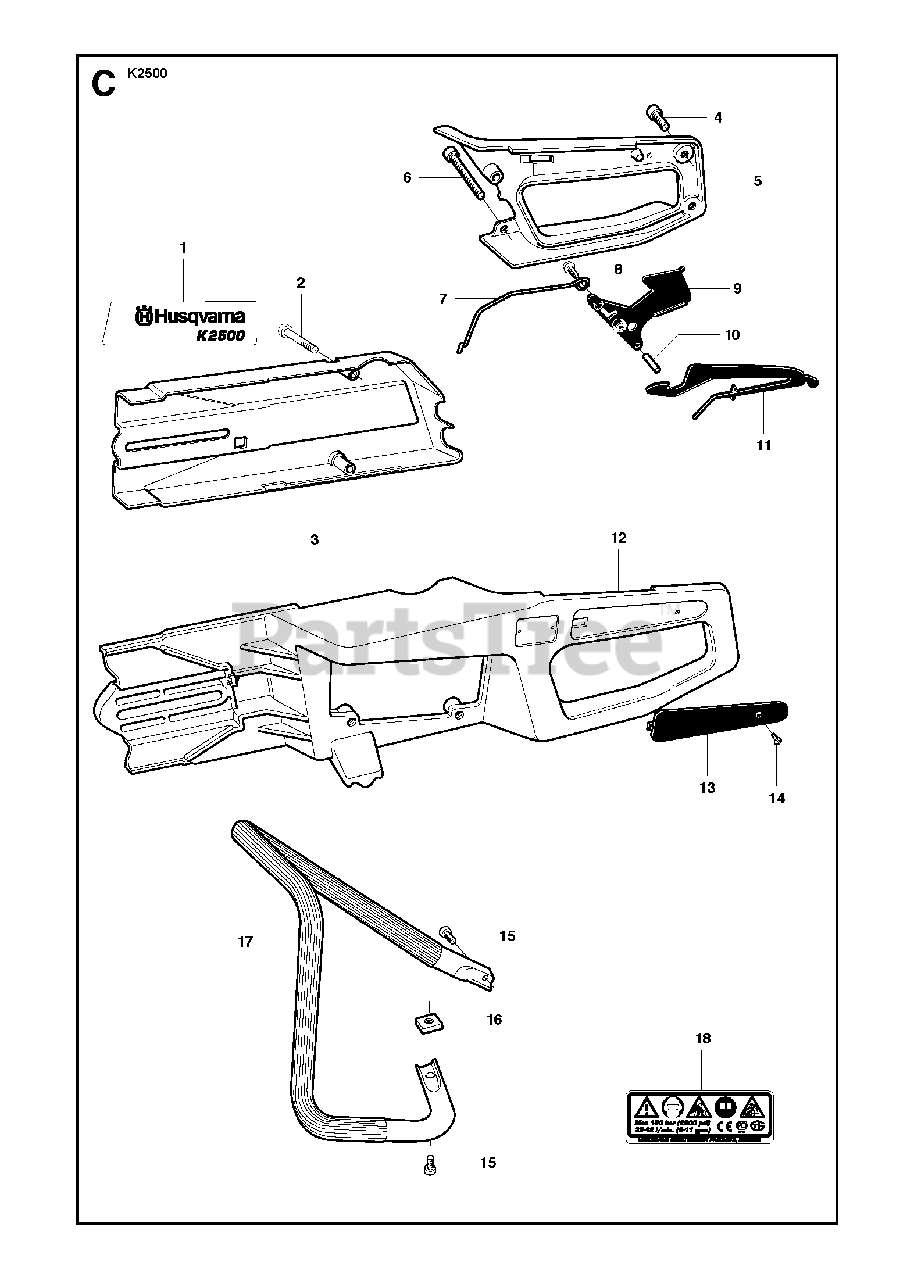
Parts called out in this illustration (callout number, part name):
2	SCREW ITXSCMNew Part
4	SCREW ITXSCMNew Part
6	SCREW ITXSCMNew Part
8	SCREW CCRPANT
10	PARALLEL PIN
11	THROTTLE LOCKOUT
13	HANDLE INSERT
15	SCREW ITXSCMNew Part
